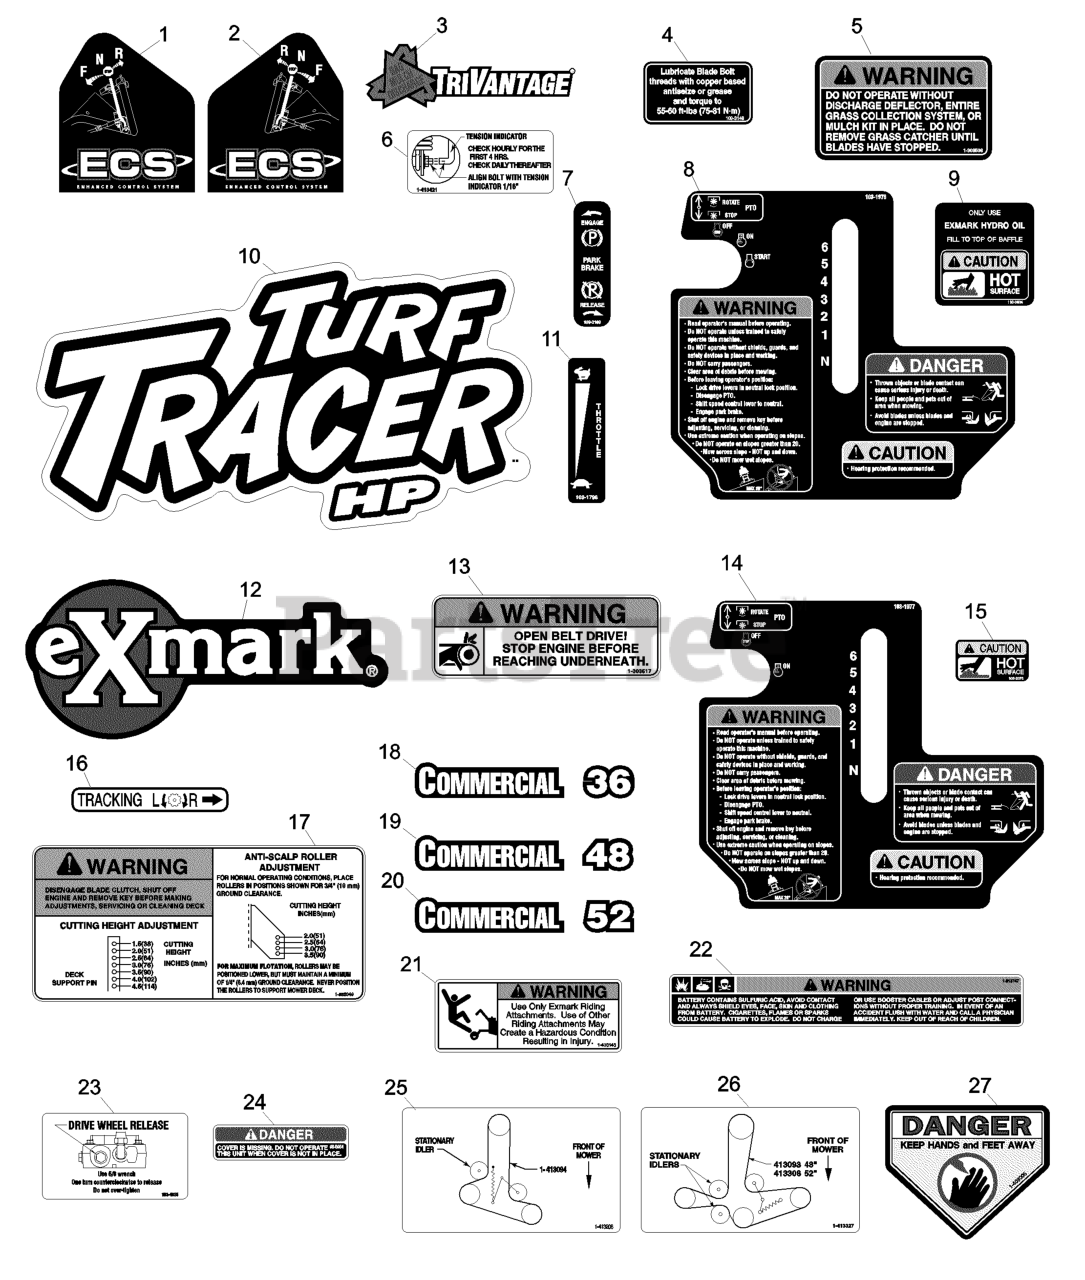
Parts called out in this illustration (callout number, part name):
1	DECAL,LH ECS INSTRUCTION
2	DECAL,RH ECS INSTRUCTION
4	DECAL,BOLT TORQUE
5	DECAL-WARNING, DISCHARGE
6	DECAL,INDICATOR
7	DECAL-BRAKE, PARK
8	DECAL,CONSOLE
9	DECAL-HYDRAULIC TANK
10	DECAL,TTHP MODEL
11	DECAL,THROTTLE ONLY
12	DECAL,EXMARK LOGO
13	DECAL,BELT DRIVE
14	DECAL,ECS CONSOLE
15	DECAL-CAUTION
16	DECAL,TRACKING ADJUST
17	DECAL,ANTI SCALP
18	DECAL,COMMERCIAL 36
19	DECAL,COMMERCIAL 48
20	DECAL,COMMERCIAL 52
21	DECAL,SULKY WARNING
22	DECAL-BATTERY
23	DECAL,DRIVE RELEASE
24	DECAL-COVER, MISSING
25	DECAL,BELT ROUTING
26	DECAL,BELT ROUTING
27	DECAL-DANGER
